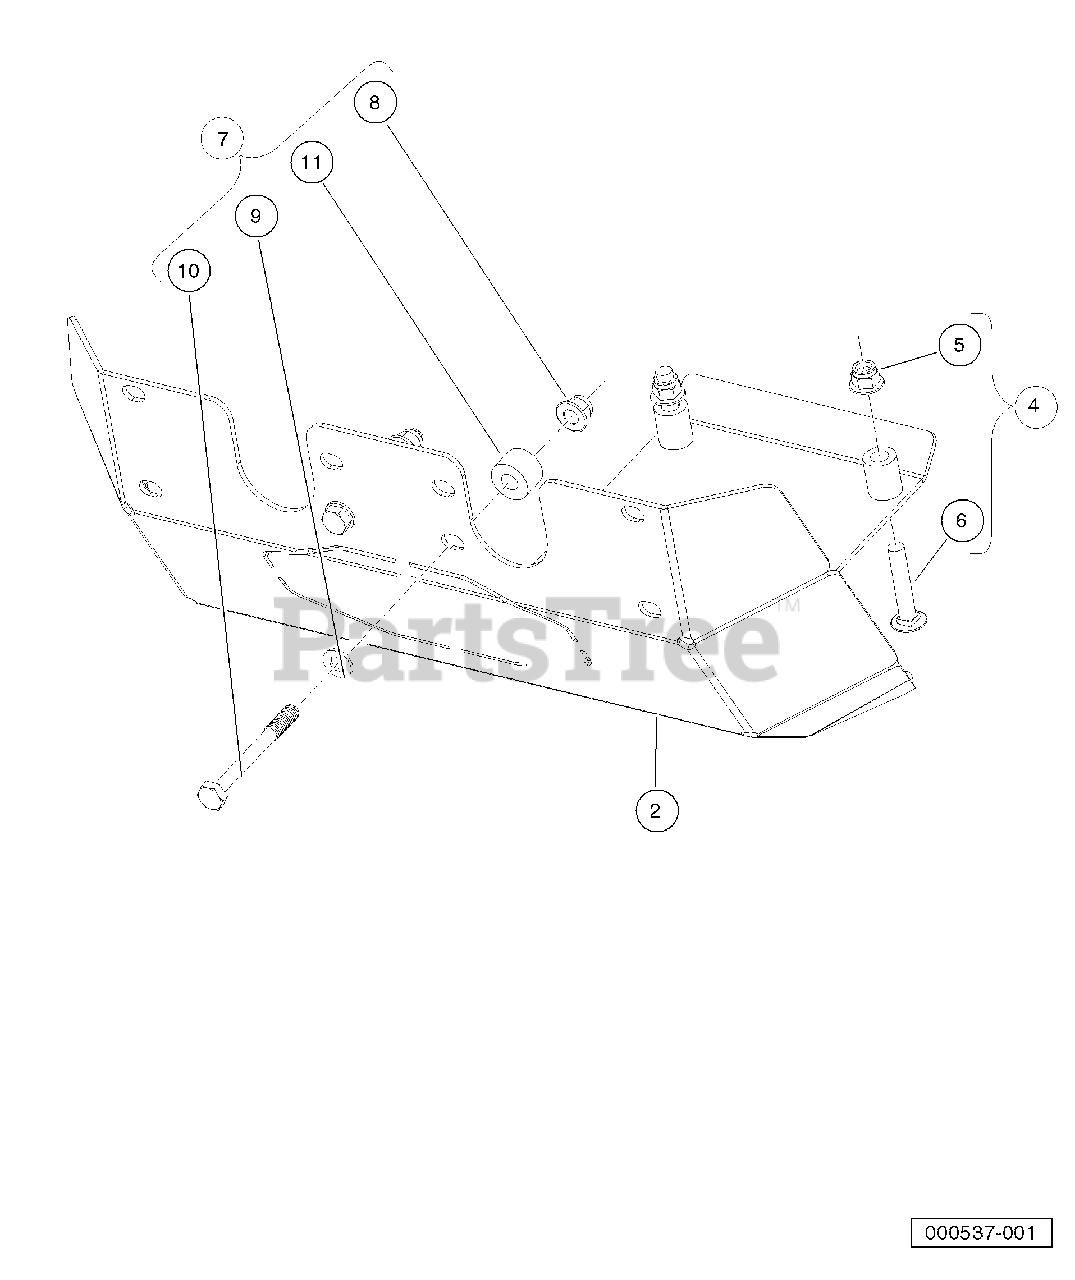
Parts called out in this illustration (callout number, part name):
1	Kit, Skidplate, Front, Steel
2	Skid Plate, Front, Steel
3	Instructions, Front Skidplate
4	Kit, Hardware, Skidplate, Front, A
5	Nut Flg M10 X 1.5 Nylon
6	Bolt, Carriage, M10x1.5x55
7	Kit, Hardware, Skidplate, Front, B
8	Nut Flg M10 X 1.5 Nylon
9	Washer, Hard, M10, Zn-Ni/Blk
10	Bolt, M10 X 1.50 X 90, Loctite
11	Spacer, 17mm Long, Skidplate
